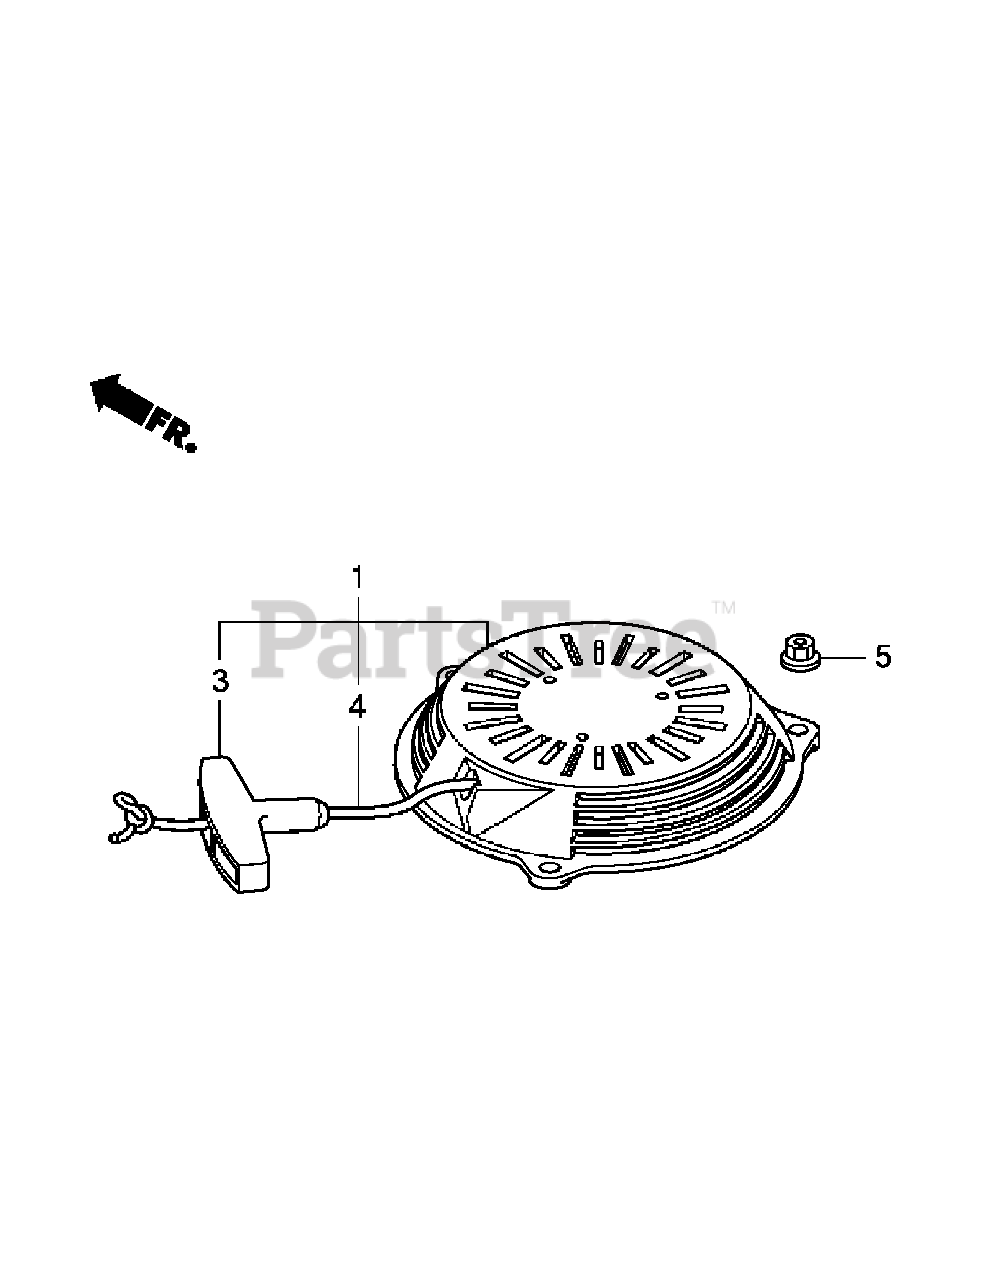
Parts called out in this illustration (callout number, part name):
1	Recoil Starter Assembly
3	Starter Grip
4	Recoil Starter Rope
5	Flange Nut, 6mm
